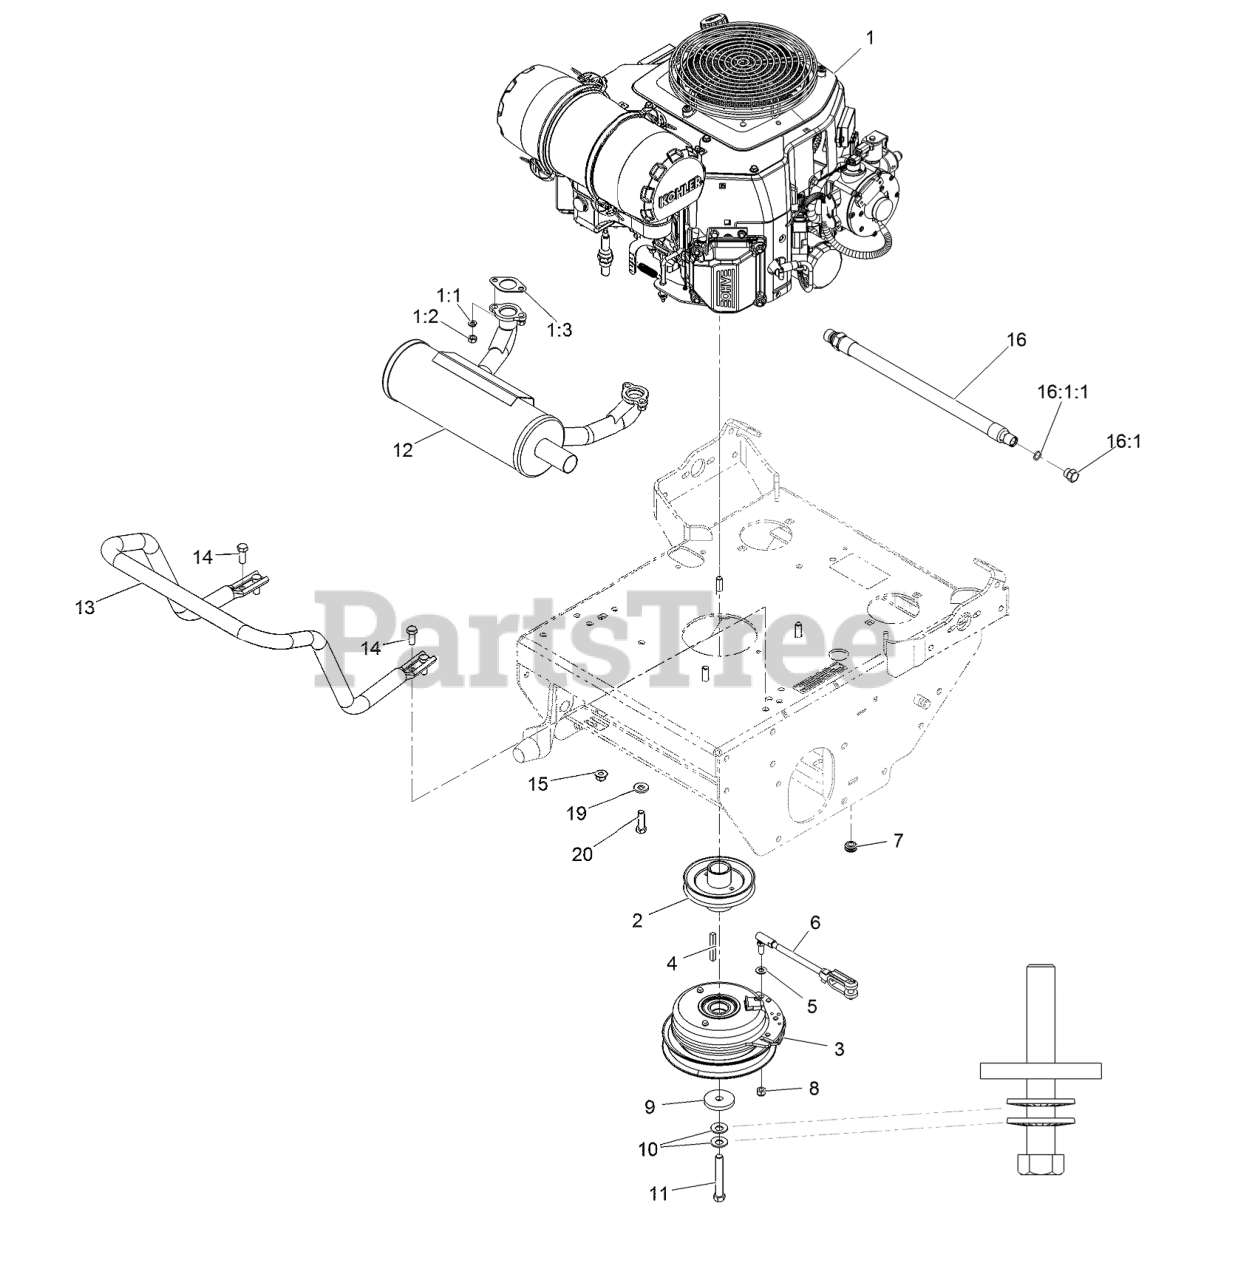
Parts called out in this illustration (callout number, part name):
1:1	WASHER-LOCK
1:3	GASKET-EXHAUST
2	SHEAVE, W/ HUB
3	CLUTCH, 105 FT/LBS, 1.13
4	KEY-SQUARE
5	WASHER-PLAIN
6	ASM, CLUTCH ANCHOR
7	GROMMET
8	NUT-LOCK
9	WASHER-CLUTCH
10	WASHER-SPRING
11	SCREW-HH
12	MUFFLER-HORIZONTAL
13	GUARD-MUFFLER
14	SCREW-HH
15	NUT-HF, NI
16	ASM, ENGINE OIL DRAIN HOS
16:1	PLUG-HH
16:1:1	O-RING
19	WASHER-BELLEVILLE
20	SCREW-HH
